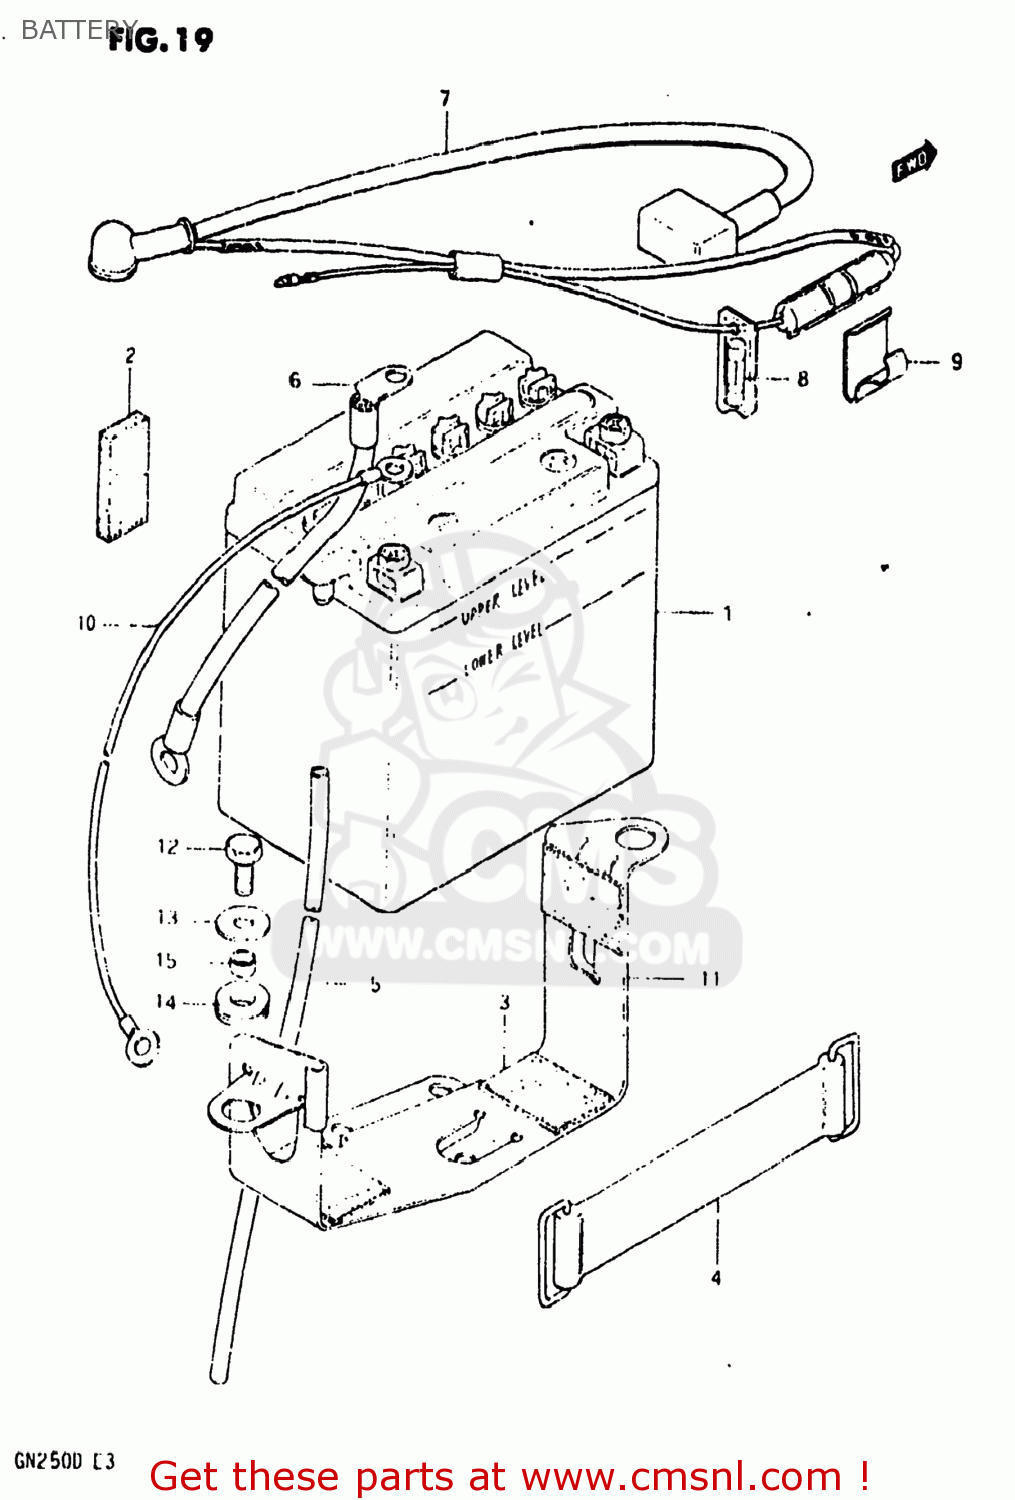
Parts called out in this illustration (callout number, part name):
1	BATTERY ASSY (12V)
2	PROTECTOR(170X95X3.0)
3	PROTECTOR(170X95X3.0)
4	BAND
5	HOSE,BATTERY EXHAUST
6	LEAD WIRE,BATTERY(-)
7	CASE ASSEMBLY,FUSE (WITH
8	FUSE(15A)
9	HOLDER,FUSE CASE
10	WIRE
11	HOLDER,BATTERY
12	BOLT, UPPER
13	WASHER (6.5X20X1.2)
14	CUSHION
15	SPACER(6.1X9X7.5)
